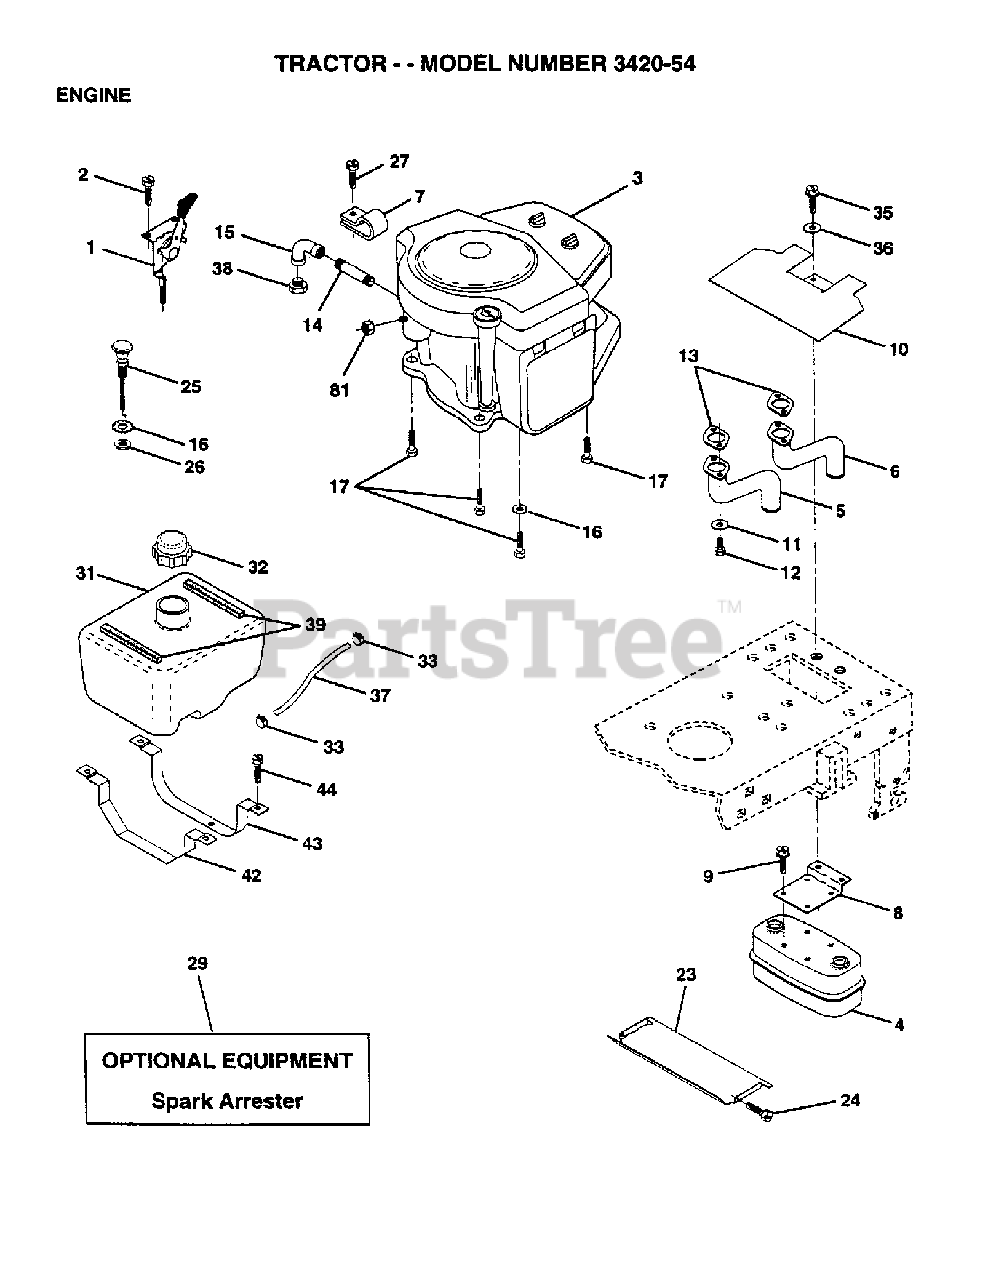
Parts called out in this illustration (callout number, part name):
1	THROTTLE CONTROL
3	Poulan TBD
5	EXHAUST ASM. LEFT
6	EXHAUST ASM. RIGHT
9	SCREW ST
10	SHIELD HEAT LT
11	LOCKWASHER
13	Poulan TBD
14	NIPPLE, PIPE 3/8NPT X 4-1/2
15	ELBOW
16	LOCKWASHER
25	CONTROL.CHOKE.51.00.BLK.W/BEND
26	NUT
27	SCREW
29	KIT.SPARK ARRESTOR(392390 B&S)
33	HOSE CLAMP
35	Screw, Lt
36	WASHER
37	LINE FUEL 7.5"
81	NUT
